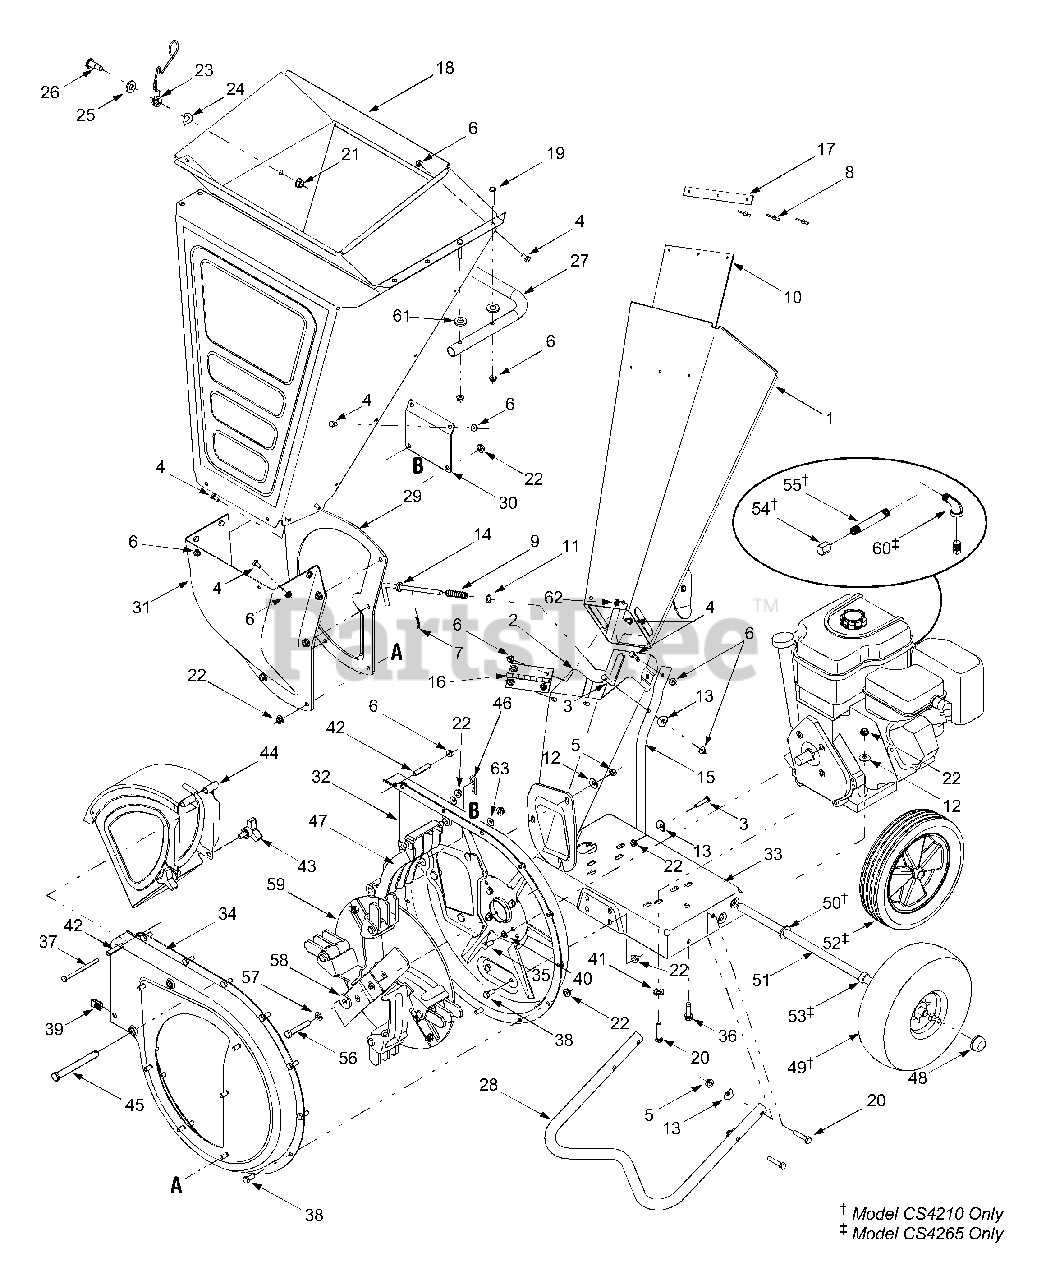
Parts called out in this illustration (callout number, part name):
3	Hex Cap Screw, 1/4-20 x 1.25
4	Hex Cap Screw, 1/4-20 x.5
5	Hex Nut, 5/16-18
6	Hex Lock Nut 1/4-20
7	Cotter Pin
8	Pop Rivet
9	Compression Spring,.531 x 1.75
10	Chute Flap
11	Flat Washer
12	Bell Washer.340 ID x.872 OD
13	Washer,.320 ID x.93 OD
14	Lock Rod
16	Chipper Chute Hinge
17	Chute Flap Strip
19	Hex Cap Screw, 1/4-20 x 1.250
20	Hex Cap Screw, 5/16-18 x 1.50
21	Flange Lock Nut, 3/8-16
22	Flange Lock Nut, 5/16-18
23	Torsion Spring
24	Spring Washer,.50 x 1.0 x.022
25	Flat Washer,.50 x 1.0 x.0125
26	Shoulder Screw, 3/8-16,.50 x.685
35	Hex Cap Screw, 5/16-24 x.75
36	Hex Sems Screw, 3/8-16 x 1.25
37	Hex Cap Screw, 1/4-20 x 3.75
38	Hex Cap Screw, 5/16-18 x.625
39	U-Nut, 5/16-18
40	Lock Washer, 5/16
41	Special Lock Washer, 5/16
42	Hinge Spacer,.265 x.380 x 1.66
43	Knob, 5/16-18
45	Clevis Pin,.50 x 4.62
46	Internal Cotter Pin
47	Shredder Screen
48	Push Cap, 5/8
49	Wheel, 10 x 4 x 4
50	Flat Washer,.625 x 1.0
51	Axle, 22.47" (CS4210)
52	Wheel, 10 x 2.5
53	Spacer,.64 x.88 x.38
54	Oil Drain End Cap
55	Oil Drain Pipe
56	Hex Cap Screw, 3/8-24 x 2.25
57	Lock Washer, 3/8
58	Flat Washer,.406 x 1.25
59	Impeller Assembly
60	Elbow Fitting
61	Flat Washer,.28 x.74 x.063
62	Push Nut,.25ID x.50OD
63	Speed Nut,.3125ID
